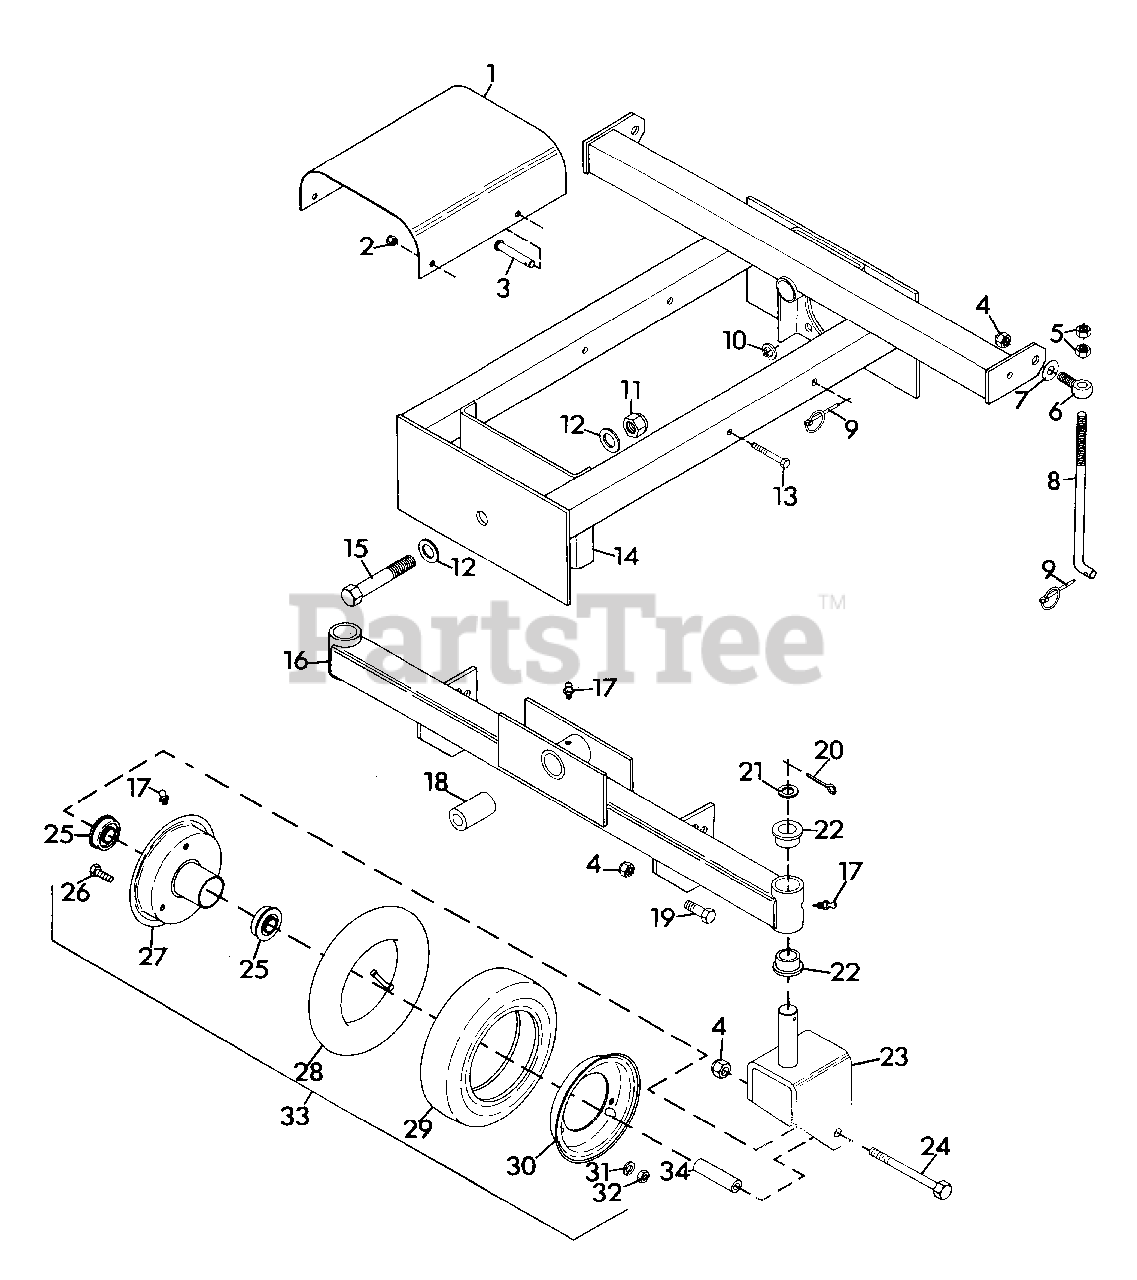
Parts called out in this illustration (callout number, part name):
1	GUARD, PTO SHAFT
2	NUT, LOCK 5/16-18
3	PIN, CLEVIS
4	NUT, LOCK 1/2-13
5	NUT, JAM 1/2-13 HEX
6	BOLT, EYE
7	WASHER, FLAT .500X1.250X.083
8	ROD, HEIGHT ADJUSTMENT
9	PIN, KLIK
10	WASHER, LOCK 1/2 REG.
11	NUT, LOCK 3/4-10
12	WASHER, FLAT .812X1.469X.130
13	BOLT, HEX 5/16-18X2.50
14	WELDMENT, MOWER FRAME
15	BOLT, HEX 3/4-10X4.50
16	WELDMENT, AXLE
17	FITTING, LUBE 1/4-28
18	TUBE, PIVOT
19	BOLT, HEX 1/2-13X1.375
20	PIN, COTTER .187X1.625
21	RACE, BEARING THRUST
22	BUSHING, PIVOT
23	WELDMENT, CASTER FORK
24	BOLT, HEX 1/2-13X5.00
25	BEARING, GAUGE WHEEL
26	BOLT, HEX 3/8-24X.75
27	WHEEL, HALF WITH HUB
28	TUBE, INNER
29	TIRE, GAUGE WHEEL
30	WHEEL, HALF PLAIN
31	WASHER, LOCK 3/8 SP HEAVY
32	NUT, HEX 3/8-24
33	WHEEL, GAUGE
34	BUSHING, WHEEL
